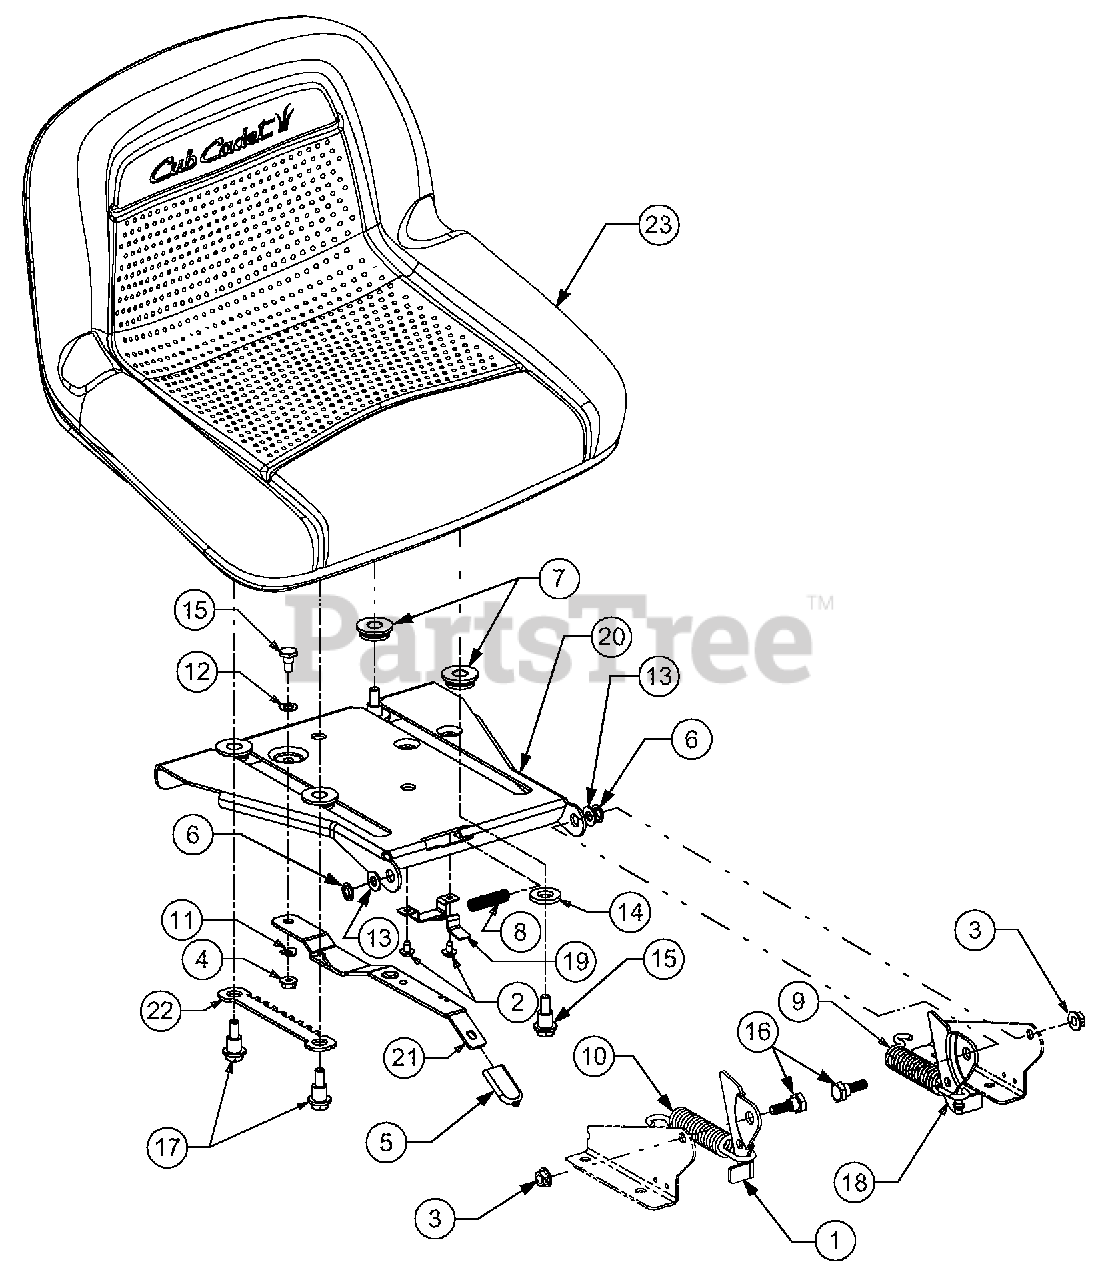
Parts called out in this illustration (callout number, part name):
1	Bracket, Seat Lift
2	Screw, #10-16, 0.375
3	Nut, Flange Lock, 5/16-18, Gr5
4	Nut, Flange Lock, 1/4-20
5	Grip, Seat, Adjustment (Yellow)
6	Nut, Speed, .3125 ID
7	Spacer, Seat, Adjustment
8	Spring, Compression .41 OD x 1.50
9	Spring, Extension, .80 Dia x 4.2 Lg.
10	Spring, Extension, .815 Dia x 4.4 Lg.
11	Washer, Spring, .265 x .562 x.025
12	Washer, Flat, .344 ID x .62 OD
13	Washer, Flat, .344 x .688 x .065
14	Washer, Flat, .531 x 1.062 x .134
15	Screw, Shoulder, .340 x .285, 1/4-20
16	Shoulder, Screw .437 x .286 Lg
17	Screw, Shoulder, .50 x.50, 5/16-18
18	Bracket, Seat Lift
19	Stop, Seat, Adjustment
22	Selector, Seat, Adjustment
23	Seat, Mid-back, V-1480
